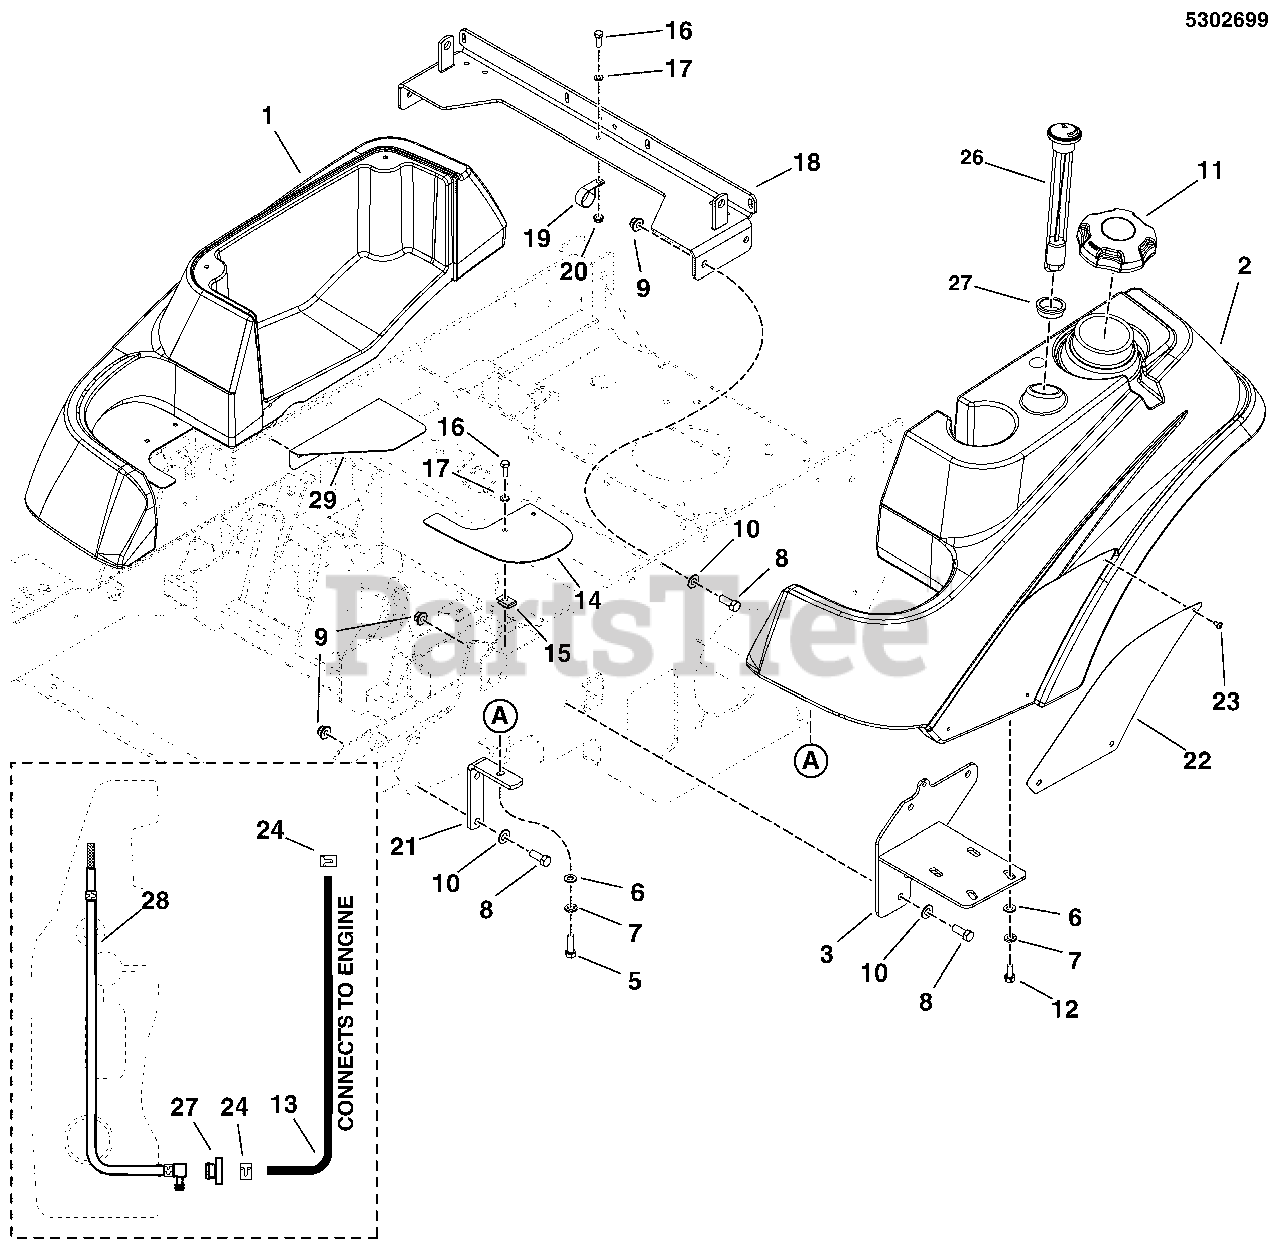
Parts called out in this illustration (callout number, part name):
1	TANK, FENDER, 1500Z - RH
2	TANK, FUEL, LH, 1500Z
3	WELD, MOUNT, FUEL TANK, LH -RED
5	BOLT, 5/16-18 X 1 GD5 YZ
6	WASHER, 5/16" SAE
7	WASHER, 5/16 LOCK YZ
8	BOLT, 3/8-16 X 1 GD5 YZ
9	NUT, 3/8-16 HEX NYLOCK FLANGE
10	WASHER, 3/8 SAE
11	FUEL CAP, 3-1/2", MANAGED VENT OUT, 12"
12	BOLT, 5/16-18 X 3/4 GD5
13	HOSE, 1/4" FUEL, 4.50"
14	GUARD, MASSEY TANK, 3000 - BLK
15	BODY CLIP, 1/4-20 X 1/2 DEEP
16	BOLT, 1/4-20 X 3/4 GD5 YZ
17	WASHER, 1/4 SAE (5025154)
18	WELD, MOUNT, HYDRO TANK - RED
19	CLAMP, VINYL INSULATED
20	NUT, 1/4-20 HEX NYLOCK FLANGE (5025391)
21	BAR, TANK MOUNT, FRONT - RED
22	PLATE, BADGE - IS1500
23	SCREW, #10-24 X 3/8 ALLEN BHBZ
24	CLAMP, HOSE, EXTERNAL, 1/2 - RED
25	BUSHING-FUEL TANK RED RUBBER (SV)
26	GAUGE, FUEL, 12
27	GROMMET, FUEL GAUGE
28	PICKUP TUBE ASM, FUEL TANK
29	PLATE, GUARD, SEAT, RH
